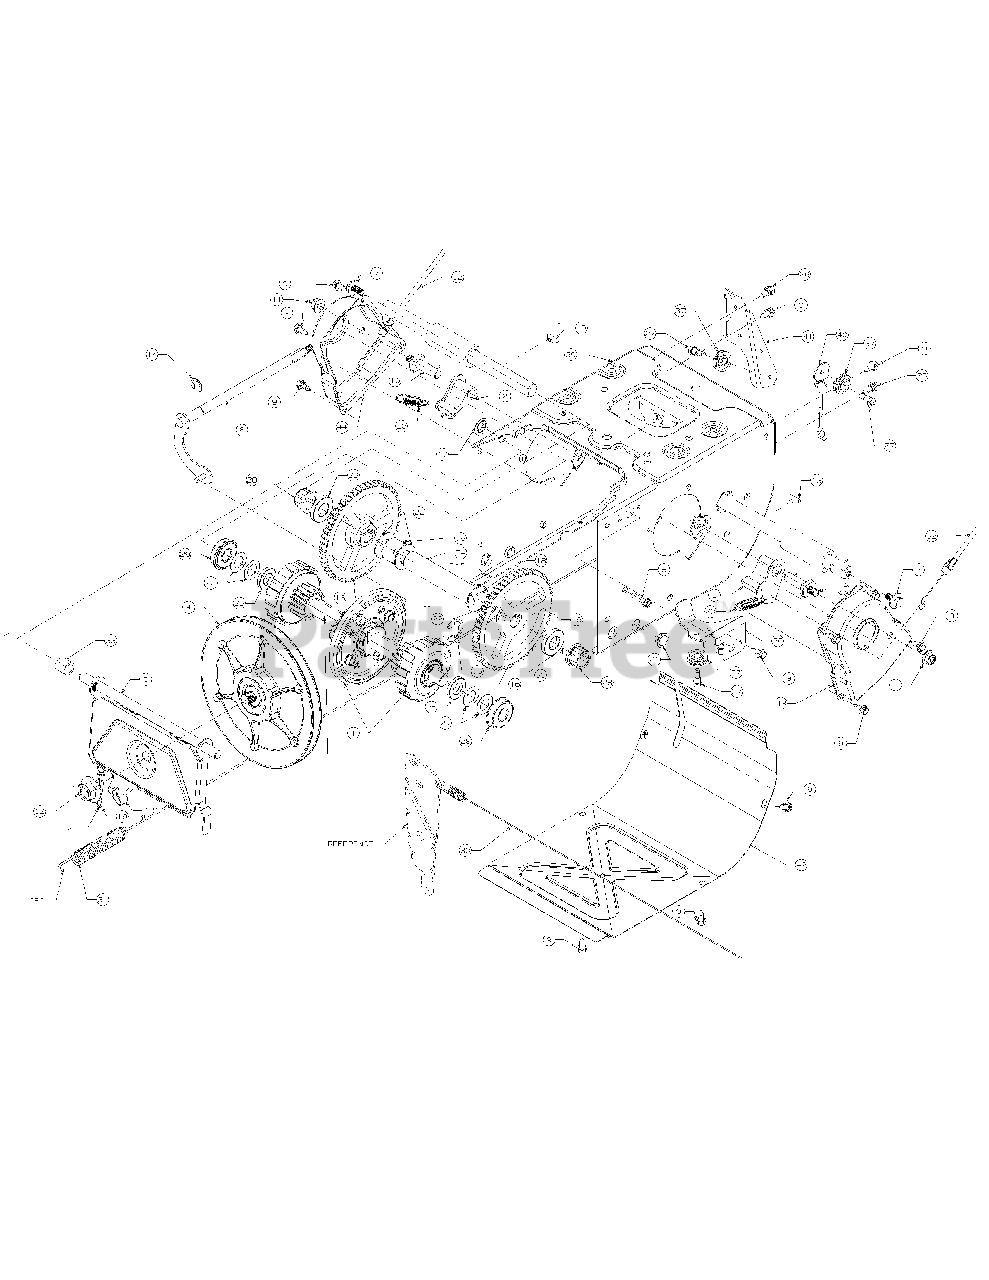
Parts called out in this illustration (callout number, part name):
1	Shift Asm-Plntr
2	Dogg Asm-RH
3	Dogg Asm-LH
4	Disc Assy-Friction
5	Bracket Assy-Support
6	Shift Asm-Rod S/T
7	Hhcs-5/16-24 X .75
8	Screw-Tap 1/4-20
9	Screw Hex.Wash.Hd
10	Shaft:Actr:Dr 500 S/
11	Nut-Flange Lk.Nylo
12	Nut-Hex Flange 5/8
13	Key 3/16 X 3/4 H
14	Ring-E For .500
15	Ring-Retaining-E T
16	Gear-56T
17	Cap-Push
18	Spacer: .76Id X .7
19	Spring-Extension
20	Spring:Extension
21	Plug-Hole 5/8
22	Washer-Fl-.760Id X
23	Washer-Flat .67X 1
24	Grease
25	Grease
26	Screw:Shoulder
27	Screw-1/4-28 X .32
28	Flange Bearing
29	Ball Bearing
30	Cable: Clutch
31	Cable-Drive Whe
32	Cable-Steering
33	Spacer-.513 Id X .
34	Tube:Supt:Axle
35	Spacer
36	Spacer-Axle
37	Roller-Cable Guide
38	Bracket-Auger Cable
39	Frame-500/700 Dr
40	Bracket:G
41	Bracket-Guide Clutch
42	Cover-Frame Snowth
43	Retainer-Strbl Drv Shf
44	Retainer-Strbl Drv Shf
